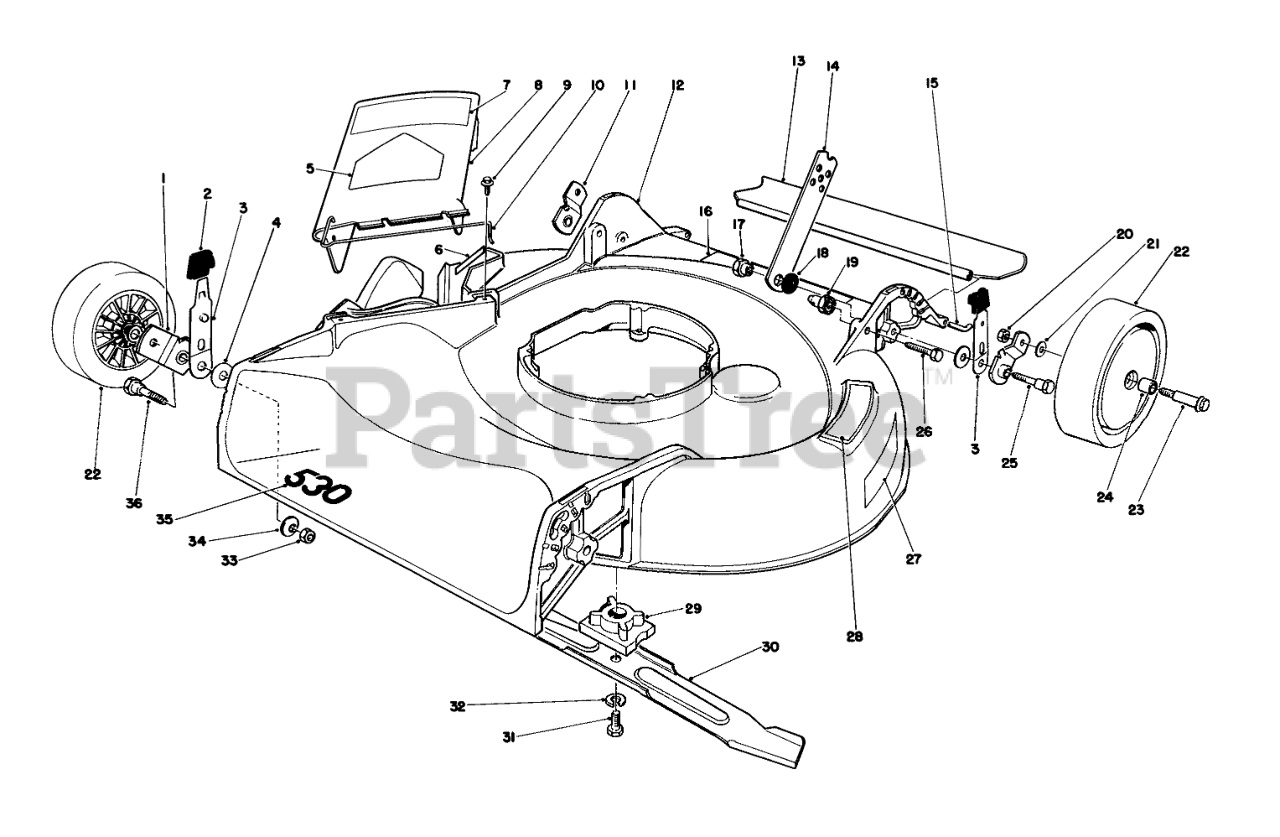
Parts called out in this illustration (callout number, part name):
1	Pivot Arm
2	KNOB-ARM
3	SPRING ARM ASM
4	WASHER-PIVOT
5	DECAL-DANGER
6	Decal-Danger
7	DANGER DECAL
8	Deflector Assembly (Incl. Ref. #5, 7 & 10)
9	SCREW-HWH
10	SPRING HINGE
11	Pivot Arm
12	HOUSING/DECAL
13	REAR SAFETY SHIELD 21
14	HANDLE LATCH
15	SHIELD ROD
16	DECAL-DANGER
17	HANDLE PIVOT NUT
18	SPACER
19	HANDLE PIVOT NUT
20	Nut
21	WASHER
22	Wheel & Tire Assembly (Incl. Ref. #24)
23	WHEEL BOLT
24	BUSHING
25	PIVOT SCREW
26	SCREW-HH
27	Decal-Place Foot Here
28	STEP PAD DECAL
29	BLADE RETAINER
30	Blade
31	SCREW-HH
32	WASHER-LOCK
33	NUT-LOCK, NI
34	WASHER-BELLEVILLE
35	Decal-530
36	5/16-18 PIVOT SCREW
